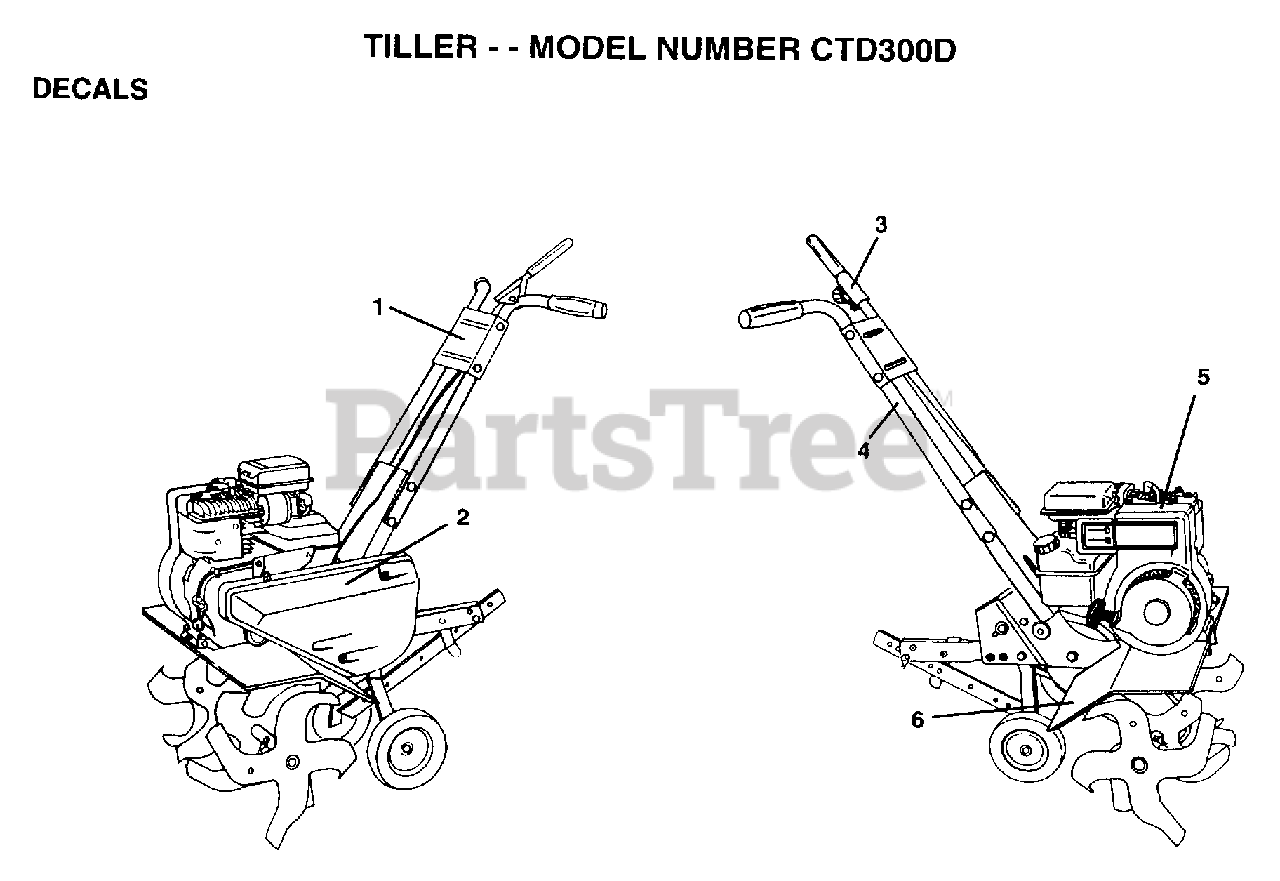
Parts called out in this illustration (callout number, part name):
1	DECAL.CNTRL.PNL.
2	DECAL.BELT.GUARD
3	DECAL TI
4	DECAL TI
6	DECAL TI
